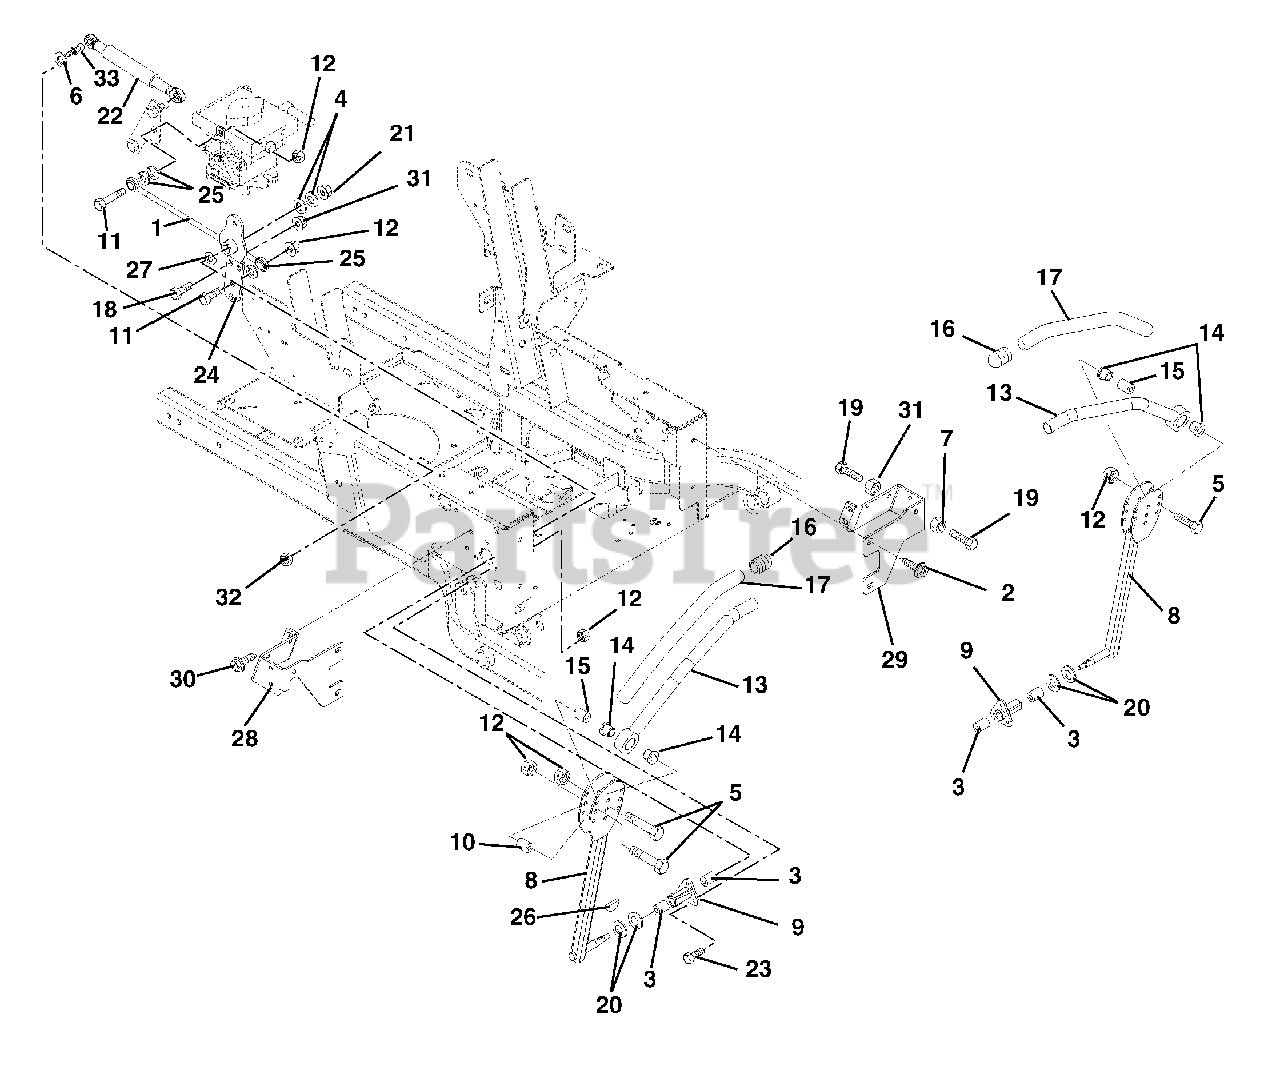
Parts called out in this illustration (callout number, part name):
1	Assembly, Steering Rod
2	Screw, Tapping .38-16 x .75 Hex Washer Head
3	Bushing .625 x .75 x .50
4	Washer, Flat Steel .38 x .875 x .083
5	Bolt, Hex .31-18 x 1.75 Grade 5
6	Washer, Flat Steel .344 x .688 x .065
7	Nut, Hex Jam .375-16
8	Control Arm
9	Housing, Bushing
10	Eccentric
11	Bolt, Hex .31-18 x 1.25 Grade 5
12	Nut, Locking Top Flange .31-18
13	Handle, Left Hand
13	Handle, Right Hand
14	Bushing, Flange Nylon .762 x 1.48 x .44
16	Caplug, Handlebar
17	Grip, Handlebar
18	Bolt, Hex .375-16 x 1.75
19	Bolt, Hex .38-16 x 1.25 Grade 5
20	Washer, Flat Steel .63 x 1.005 x .062
21	Nut, Locking Top Flange .38-16
22	Damper, Control
23	Bolt, Hex .31-18 x .75 Grade 5
24	Arm, Pivot
25	Washer, Locking .31 x .078 Regular
26	Key, Woodruff .13 x .63
27	Wave Washer
28	Stop, Steering - Right Hand
29	Stop, Steering - Left Hand
30	Screw, Tapping .38-16 x .50 Hex Washer Head
31	Nut, Locking Jam Center .375-16
32	Nut, Locking Nylon M8-1.25
33	Stud, Ball
